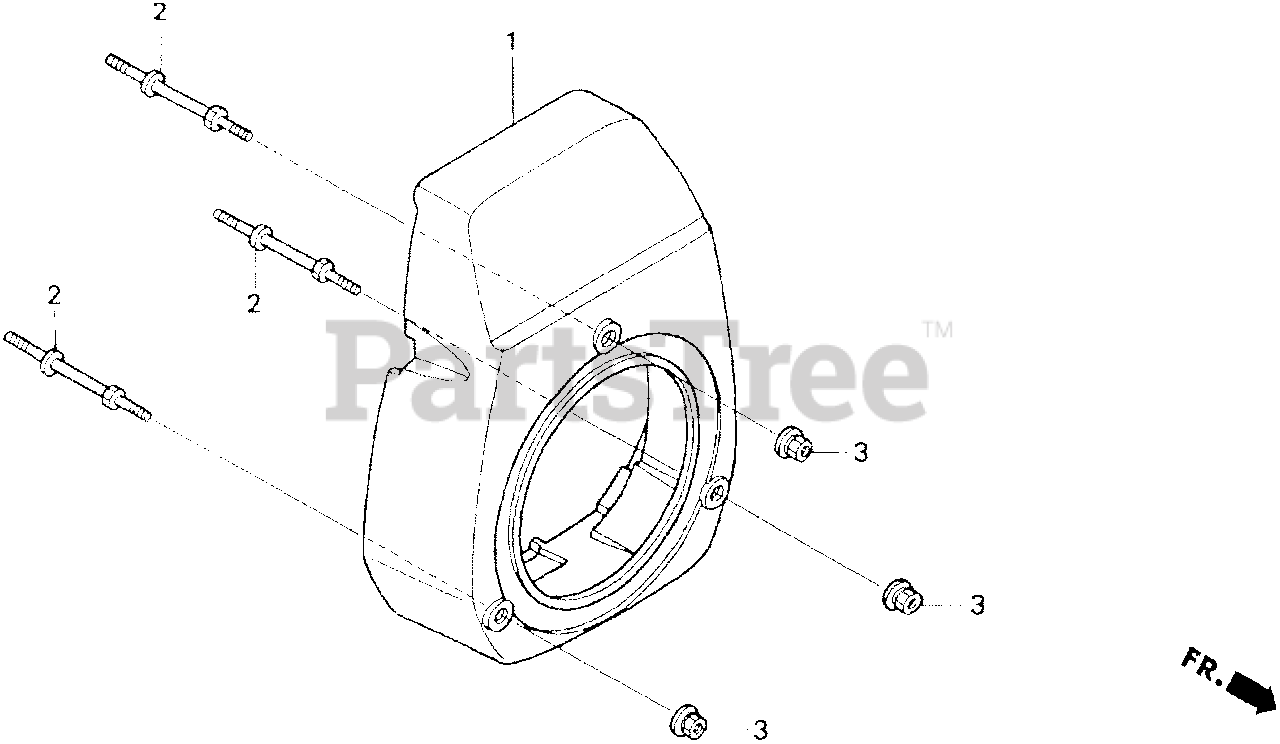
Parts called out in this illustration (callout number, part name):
1	COVER, FAN *R8* (BRIGHT RED)
1	COVER, FAN *R280* (POWER RED)
2	BOLT, STUD
3	NUT, FLANGE (6MM)
